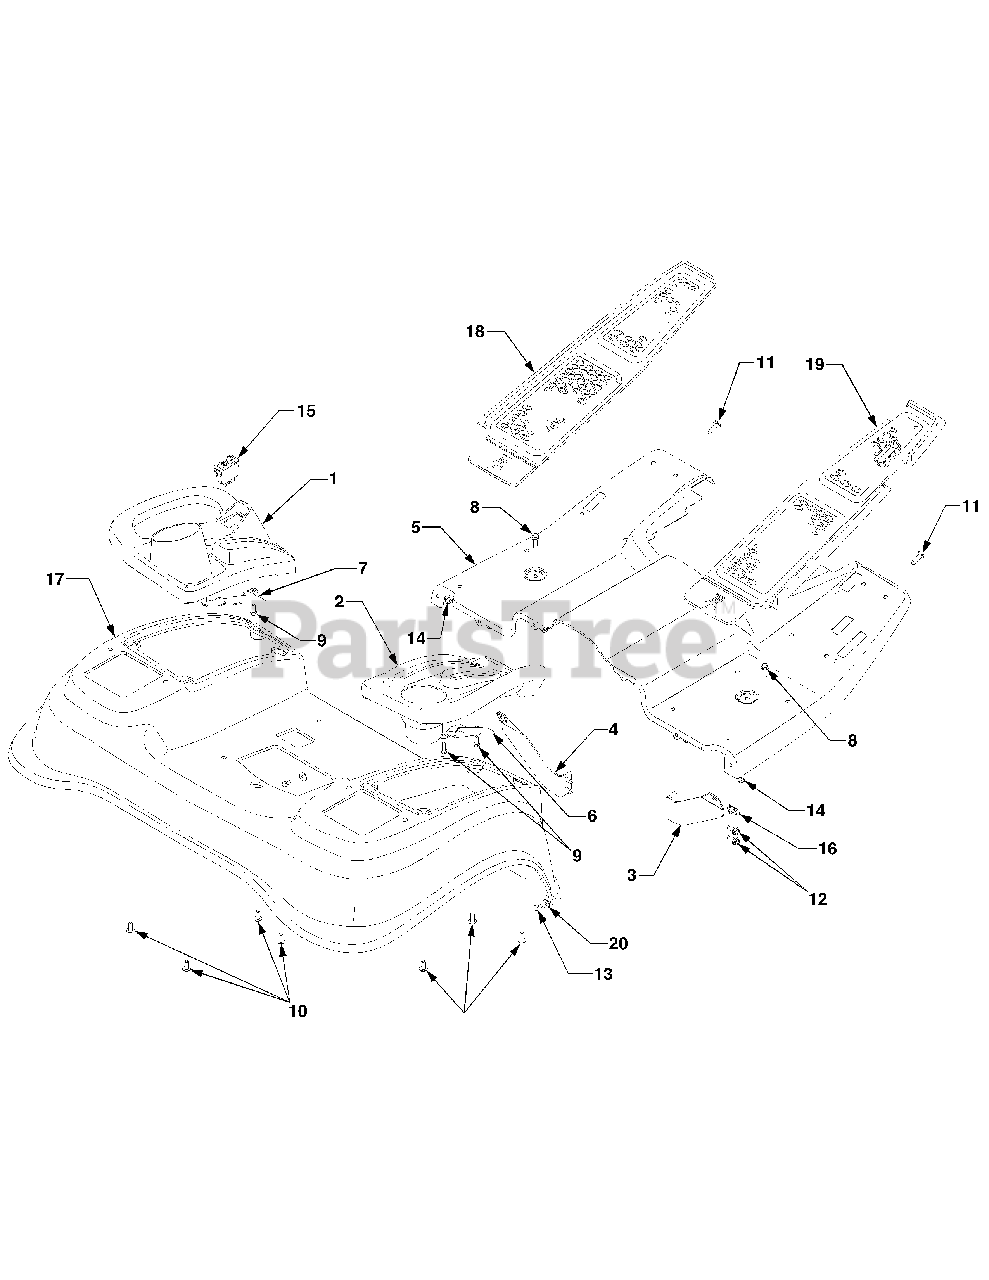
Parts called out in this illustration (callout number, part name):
1	Cover, Fender, LH
2	Cover, Fender, RH
3	Bracket, Running Brd Mtg. RH
4	Bracket, Running Brd Mtg. LH
5	Running Board
9	Screw, Hex Wash. Hd, Tapp
10	Screw, Truss Phillips Hd.
11	Screw, Pan Hd. 5/16-18 x 1.0
12	Screw, Hex Wash. Hd. Tapp
13	Screw, Hx. Cap, 1/4-20 x .5 GR5
14	Nut, Hx. Insert Lck, 1/4-20 GR8
15	Switch, PTO Reverse
16	Nut, Speed, 5/16-18
17	Fender
18	Pad, Floor - LH
19	Pad, Floor - RH
20	Washer, Flat, .26 x .72 x .06 .
